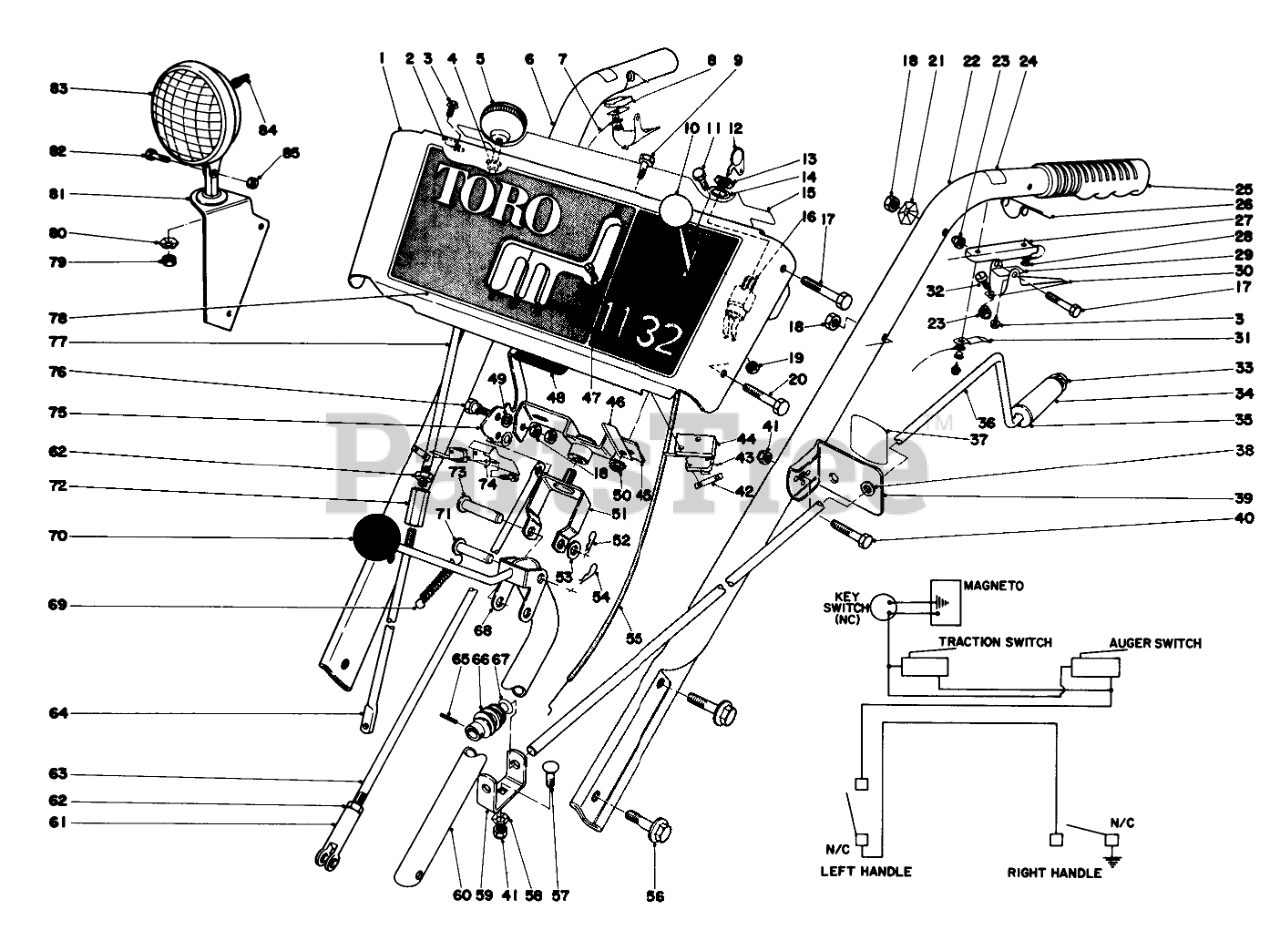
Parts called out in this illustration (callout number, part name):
1	Escutcheon Plate (Incl. Ref. #15 & 78)
2	PLASTIC CLIP
3	SCREW
4	NYLINER #6LI-FF TYPE 7
5	KNOB-LEVER
6	Handle Right
7	WIRE HARNESS
8	Insulator
9	SCREW-HH
10	CONTROL KNOB
11	HEX HEAD SEMS 10-24X1/2
12	Key
13	NUT-HH
14	WASHER-TOOTH, INTERNAL
15	Decal-Escutcheon Back
16	SWITCH-ON / OFF
17	SCREW-HH
18	NUT-LOCK, CONE
19	Nut
20	SCREW-HH
21	Washer
22	LEFT HANDLE
23	NUT-CAP
24	INTERLOCK DECAL
25	Grip Handle
26	INTERLOCK SPRING
27	DUAL BRKT INSULATOR
28	WASHER INSULATOR
29	INTERLOCK CONTACT
30	SAFETY INTRLOCK LEVER
31	CONTACT BRACKET
32	NYLON SCREW 1/4 20
33	RETAINER-PUSH ON
34	CHUTE CONTROL GRIP
35	WASHER-FLAT
36	ROD CHUTE CONTROL
37	CHUTE DECAL
38	Bushing
39	Bracket Chute Control Mounting (Incl. Ref. #37 & 38)
40	SCREW-HH
41	NUT-LOCK, NI
42	NUT-SPEED
43	MICRO SWITCH
44	SWITCH MTG PAD
45	SWIVEL BLOCK WA
46	Retainer Wire
47	SCREW-SPH
48	AUGER CLUTCH HND GRIP
49	WASHER-PLAIN
50	NUT-LOCK, HHF
51	PIVOT BRKT WA
52	PIN-HAIR
53	WASHER-FLAT
54	PIN-COTTER
55	Throttle Contrl
56	SCREW-HHF
57	BOLT-CARR
58	WASHER-LOCK
59	WORM BRACKET
60	Rod Traction Shift
61	Clevis
62	NUT-HJ
63	DRAG LINK
64	LOWER WHL CLUTCH ROD
65	PIN-SPRING
66	GEAR-WORM, CHUTE
67	WASHER-SPRING
68	SHIFT ROD WA
69	CONT ROD SPRING 0
71	PIN-CLEVIS
72	WHL ROD COUPLING
73	PIN-CLEVIS
74	SWITCH BRKT
75	Auger Clutch Handle
76	SCREW-SHOULDER
77	UP WHEEL CLUTCH ROD
78	Decal-Escutcheon
79	NUT-HEX
80	LOCKWASHER-PYRAMID
81	Lamp Mount
82	SCREW-HH
83	HEADLAMP ASM
84	BOOT-SWITCH
85	NUT-HEX, SIDE DEFORM
